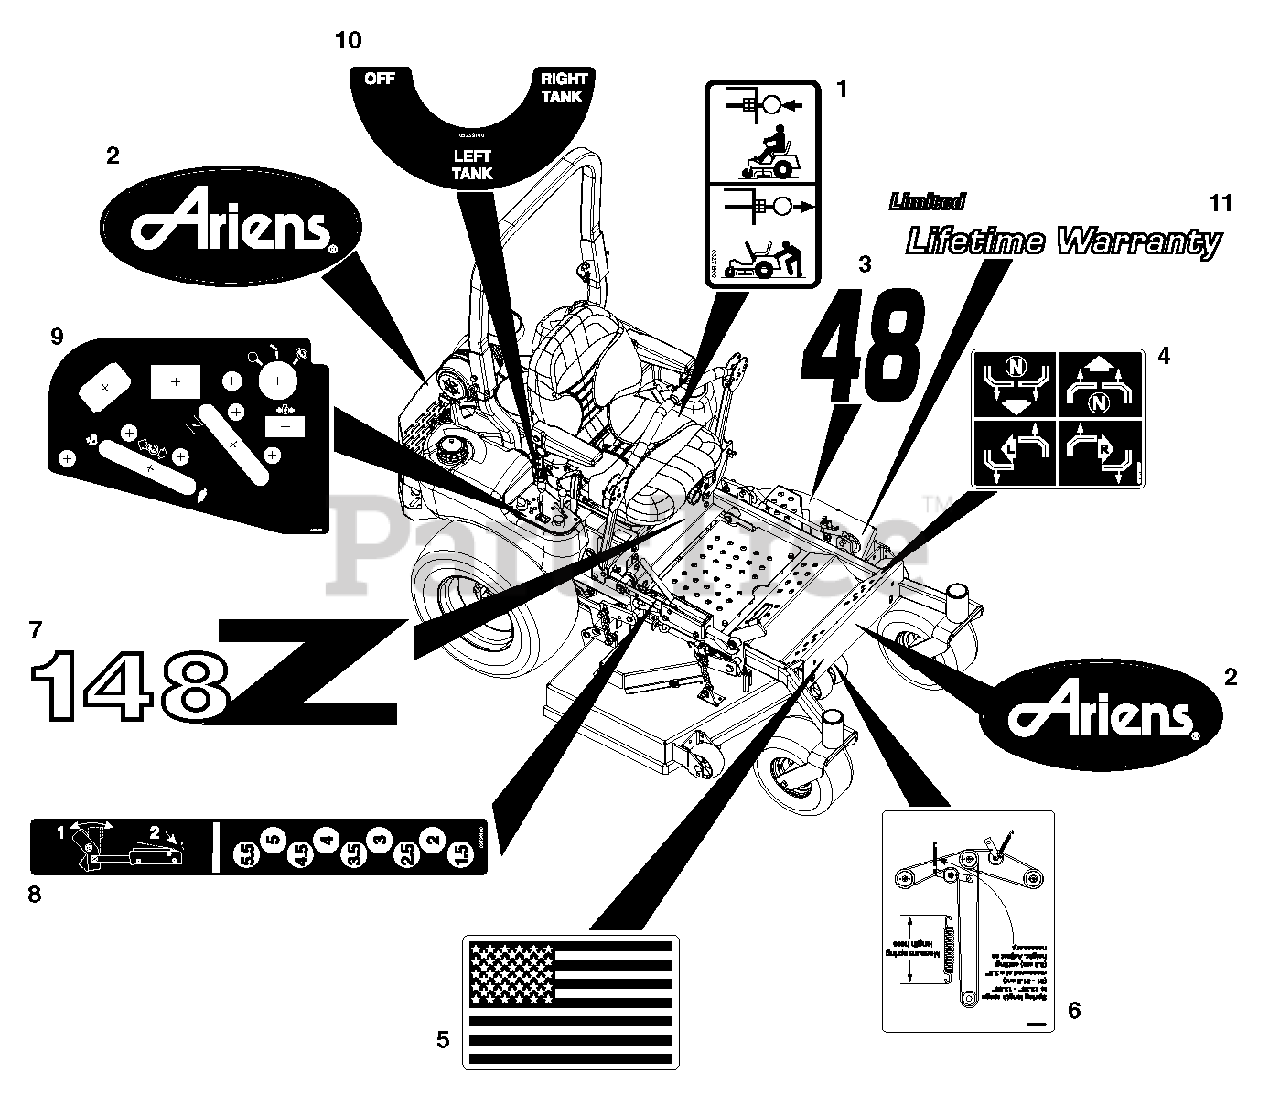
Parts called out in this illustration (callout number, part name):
1	Decal, Transmission Disconnect
2	Decal, Ariens
3	Decal, 48
4	Decal, Instructional- Steering
5	Decal, American Flag
6	Decal, Belt Routing
7	Logo, 148Z
8	Decal, Height of Cut
9	Decal, Control Panel
10	Decal, Fuel Valve
11	Decal, Limited Lifetime Warranty
